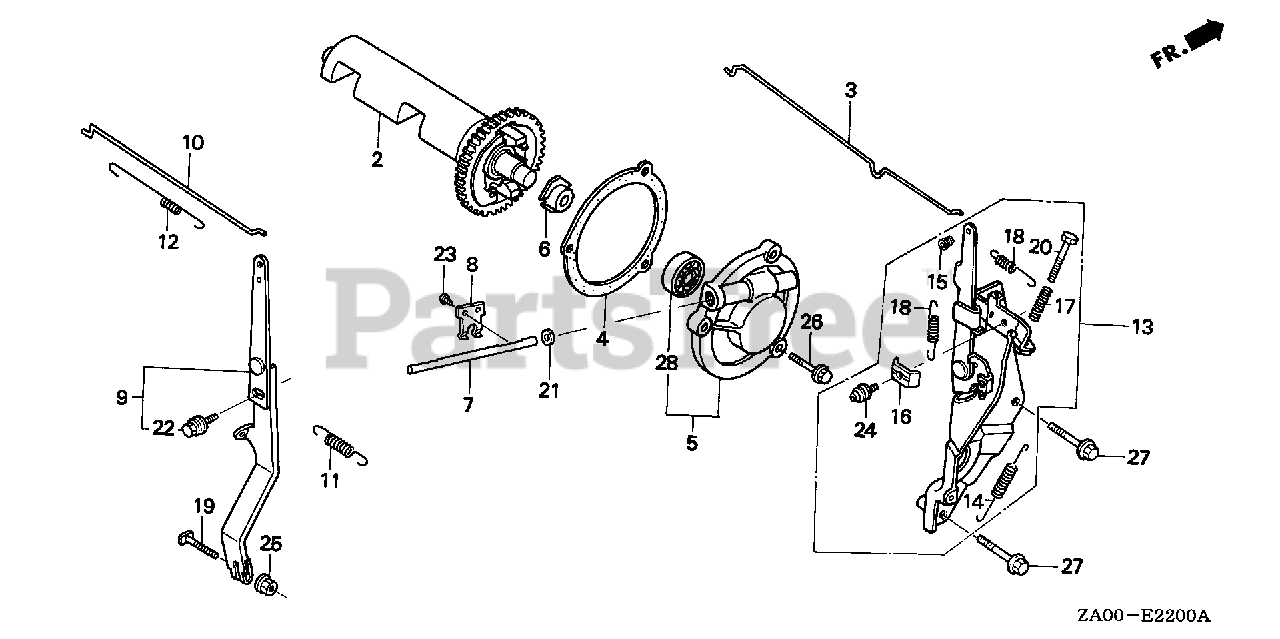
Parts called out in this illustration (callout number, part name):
2	WEIGHT, BALANCER
3	ROD, CHOKE
4	GASKET, GOVERNOR COVER
5	COVER, GOVERNOR
6	SLIDER, GOVERNOR
7	SHAFT, GOVERNOR ARM
8	FORK, GOVERNOR
9	ARM, GOVERNOR
10	ROD, GOVERNOR
11	SPRING, GOVERNOR
12	SPRING, THROTTLE RETURN
13	CONTROL
14	SPRING, CONTROL LEVER RETURN
15	COLLAR, LEVER
16	HOLDER, CABLE
18	SPRING, CABLE RETURN
19	BOLT, GOVERNOR ARM
21	OIL SEAL (8X14X5)
22	BOLT-WASHER (6X12)
23	SCREW, PAN (3X8)
24	SCREW, PAN (5X16)
25	NUT, FLANGE (6MM)
26	BOLT, FLANGE (6X25)
27	BOLT, FLANGE (6X40)
27	BOLT, FLANGE (6X45)
28	BEARING, RADIAL BALL (6202)
